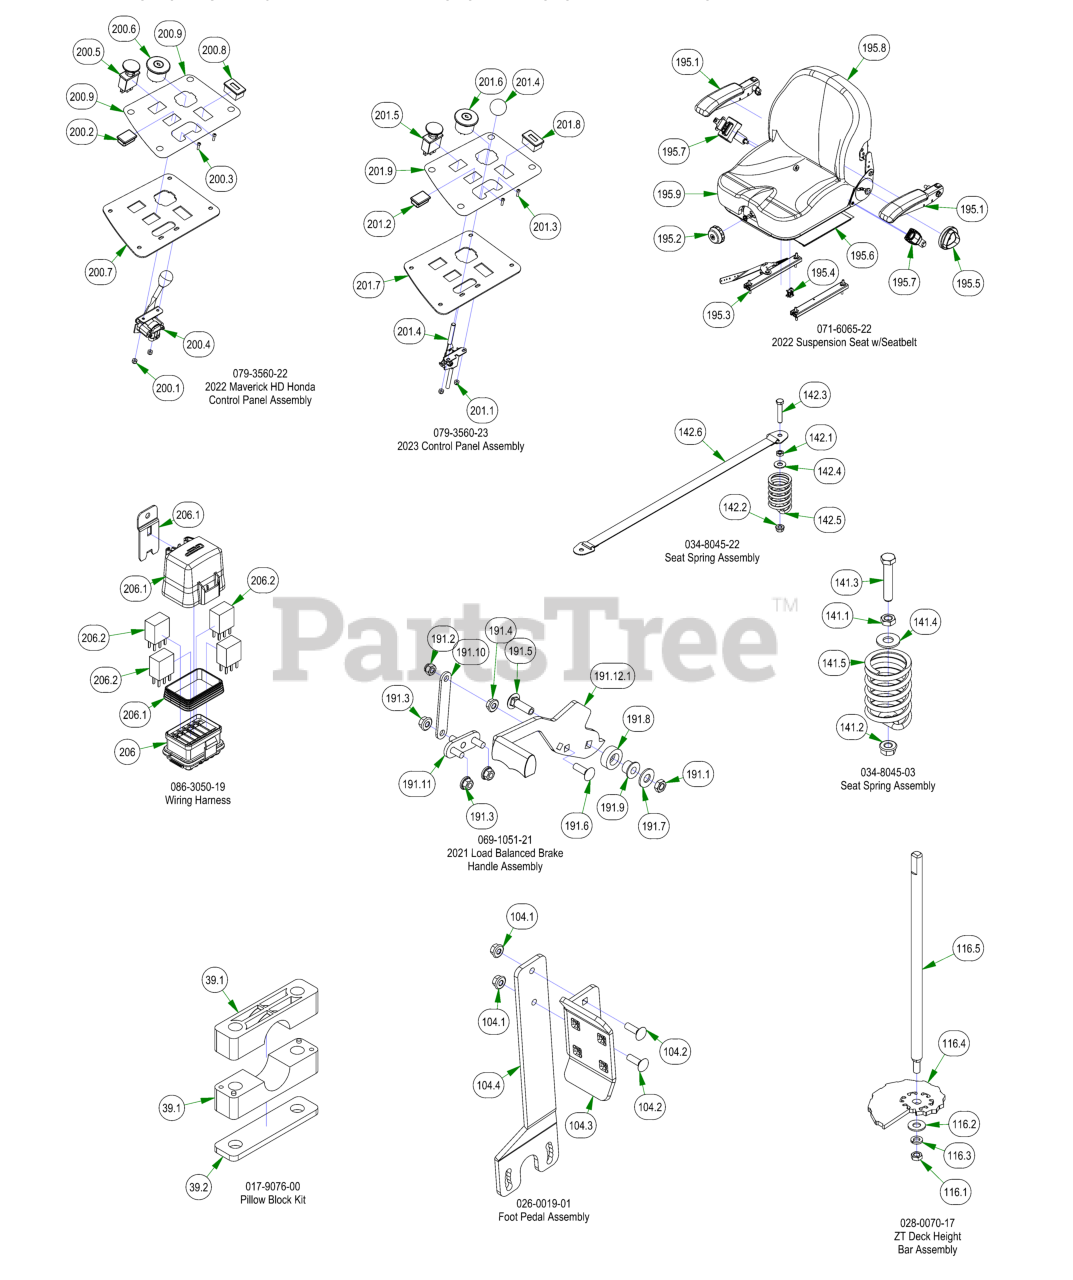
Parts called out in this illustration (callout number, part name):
39	Pillow Block Kit
39.1	Pillow Block MZ
39.2	Pillow Block Strap
59	5/16-18 X 1-1/4 CARRIAGE BOLT ZINC
104	Foot Pedal Assembly
104.1	5/16-18 NYLON INSERT FLANGE LOCKNUT ZINC
104.2	5/16-18 X 1 CARRIAGE BOLT (GR.8) ZINC
104.3	2017 MZ/ZT Shallow Foot Pedal
104.4	2017 MZ/ZT Deck Pedal Lever
108	2023 4" & 5" Stripping Kit Plate
116	ZT Deck Height Bar Assembly
116.1	3/8-24 HEX NUT ZINC YELLOW
116.2	3/8 FLAT WASHER USS (1" OD) ZINC
116.3	3/8 SPLIT LOCKWASHER ZINC
116.4	2017 MZ/ZT Cam Plate
116.5	2017 Deck Height Dial Rod ZT
141	Seat Spring Assembly
141.1	3/8-16 Half Jam Nut
141.2	3/8-16 HEX SERRATED FLANGE NUT HARD/ZINC
141.3	3/8-16 X 2 HEX CAP SCREW (GR.5) ZINC
141.4	3/8 FLAT WASHER USS (1" OD) ZINC
141.5	Seat Spring
142	Seat Spring Assembly
142.1	3/8-16 Half Jam Nut
142.2	3/8-16 HEX SERRATED FLANGE NUT HARD/ZINC
142.3	3/8-16 X 2 HEX CAP SCREW (GR.5) ZINC
142.4	3/8 FLAT WASHER USS (1" OD) ZINC
142.5	Seat Spring
142.6	Seat Strap with Buckles
191	2021 Load Balanced Brake Handle Assembly
191.1	3/8-16 HEX JAM 2-WAY REVERSIBLE CENTER LOCKNUT ZINC
191.2	5/16-18 NYLON INSERT CAP LOCKNUT ZINC (BLK CAP)
191.3	5/16-18 NYLON INSERT FLANGE LOCKNUT ZINC
191.4	5/16-18 HEX SERRATED FLANGE NUT HARD/ZINC
191.5	3/8-16 X 1-1/4 CARRIAGE BOLT ZINC
191.6	5/16-18 X 1 CARRIAGE BOLT (GR.8) ZINC
191.7	3/8 FLAT WASHER USS (1" OD) ZINC
191.8	2015 Brake Lever Spacer
191.9	.377 ID X .625 OD X .500 HGT X .880 FLNG DIA X .060 FLNG THK
191.10	Brake Cable Extension Plate
191.11	Brake Load Balancer Lower Weldment
191.12	Load Balanced Brake Handle with Grip
191.12.1	Switch Relocation Brake Handle
191.12.2	Brake Handle Rubber
195	2022 Suspension Seat w/Seatbelt
195.1	Set of Armrests-SS Front Adj
195.2	Weight Adjust Indicator Knob Assy
195.3	4" Single Locking Track Kit
195.4	Delta Plunger Switch - N.O.
195.5	Recliner Adjustment Knob-New
195.6	Bellows w/Hardware
195.7	2" Retractable Belt Kit w/Spacers
195.8	Back Cover for I3M - Recl - Logos
195.9	Cushion Cover Kit for I3M-Logo
200	2022 Maverick HD Honda Control Panel Assembly
200.1	10-24 Nylon Insert Locknut Zinc Orange Nylon
200.2	Light Plug
200.3	10-24 X 5/8 BS Button Head Bolt
200.4	Honda Drive By Wire
200.5	PTO Engager
200.6	Ignition Switch
200.7	2022 Maverick HD control panel
200.8	Tachometer
200.9	2023 MZ/Magnum/ZT/Maverick Control Panel Decal
201	2023 Control Panel Assembly
201.1	10-24 Nylon Insert Locknut Zinc Orange Nylon
201.2	Light Plug
201.3	10-24 X 5/8 BS Button Head Bolt
201.4	Throttle Lever Assembly
201.5	PTO Engager
201.6	Ignition Switch
201.7	2022 Maverick HD control panel
201.8	Tachometer
201.9	2023 MZ/Magnum/ZT/Maverick Control Panel Decal
202	2023 ZT Stripping Kit Rubber
206	Wiring Harness
206.1	Relay Block Cover Replacement Kit
